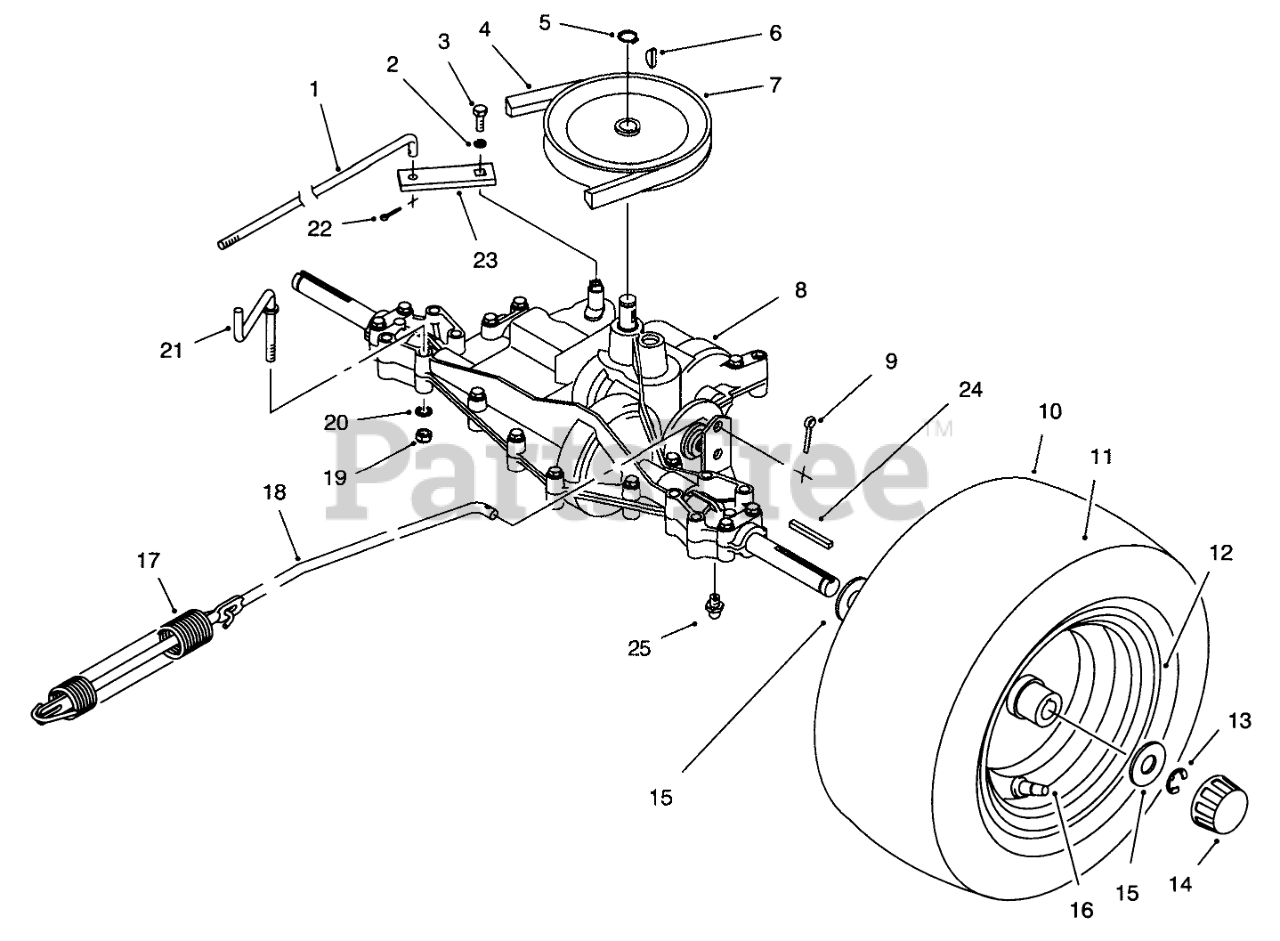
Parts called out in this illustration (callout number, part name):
1	LINK-SHIFT
2	WASHER-LOCK
3	SCREW-HH
4	V-BELT, TRACTION
5	RING-SNAP, EXTERNAL
6	KEY-WOODRUFF
7	PULLEY-TRANSAXLE
8	TRANSAXLE 915-019
9	PIN-COTTER
11	TUBE-INNER
12	REAR WHEEL ASM
13	E-RING
14	CAP-HUB
15	WASHER-PLAIN
16	STEM-VALVE
17	SPRING-EXT
18	ROD-BRAKE
19	NUT-LOCK, NI
20	WASHER-LOCK, INTERNAL
21	GUIDE-LOWER BELT
22	PIN-COTTER
23	LINKAGE
24	KEY-SQUARE
25	FITTING-GREASE
